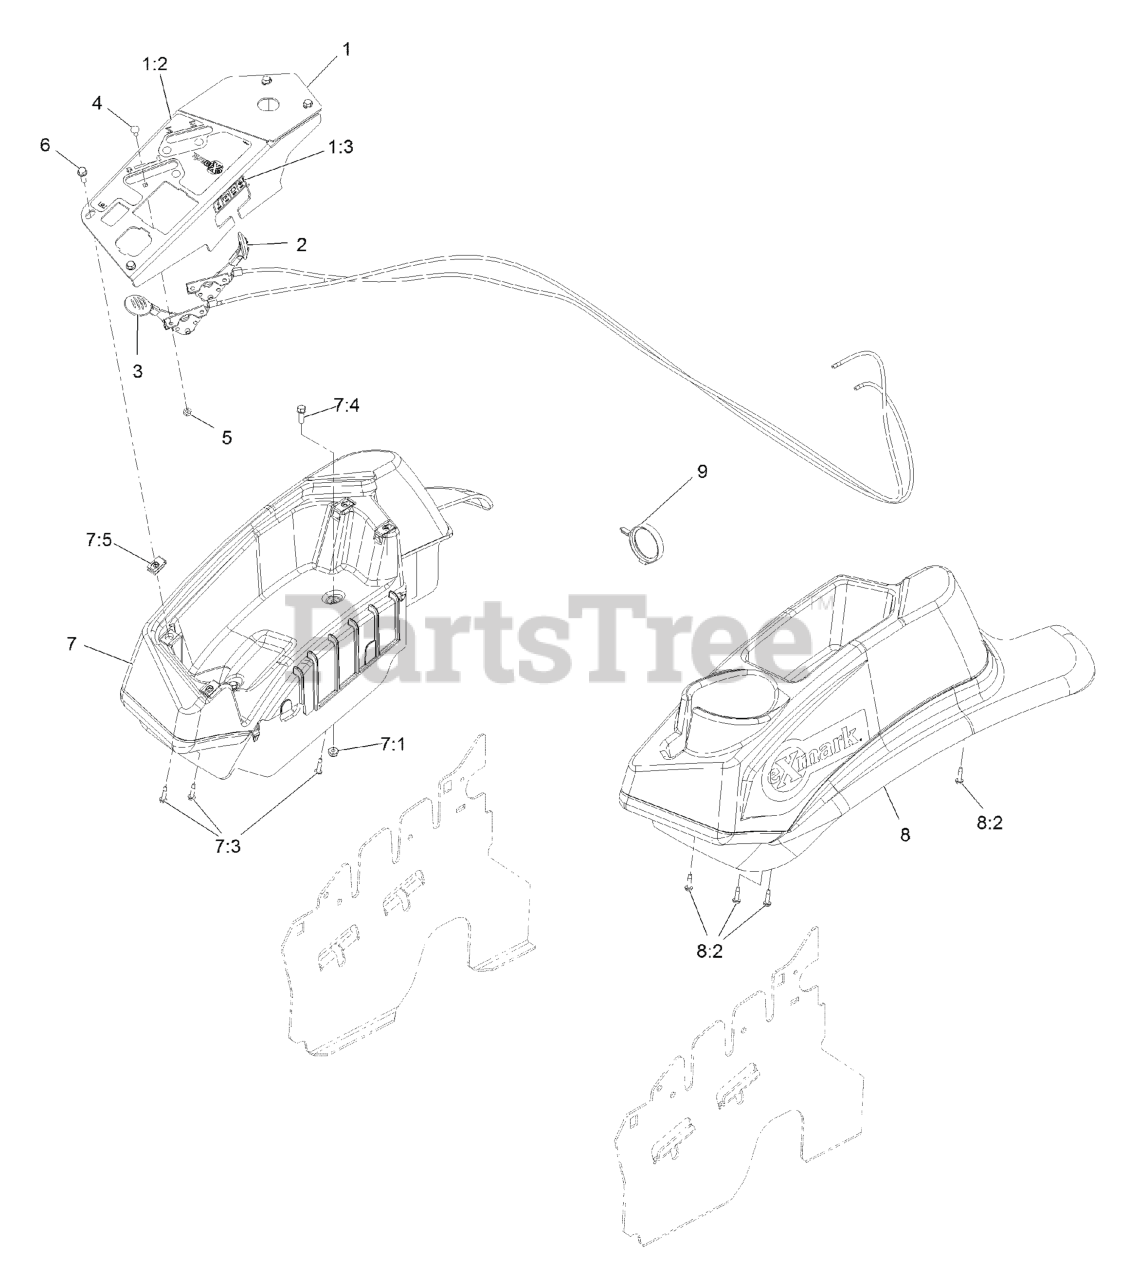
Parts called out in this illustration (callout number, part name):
1	CONSOLE,PANEL W/DECAL
1:2	DECAL-CONTROL PANEL NON-E
1:3	DECAL-FUSES
2	ASM, CHOKE CABLE
3	ASM,THROTTLE CABLE
4	BOLT-CARR
5	NUT-LOCK, NI
6	SCREW-HWH
7	CONSOLE,RH NARROW ASM
7:3	SCREW,THD FORM,HWH
7:4	SCREW-HWH
8	CONSOLE.LH NARROW ASM
8:2	SCREW,THD FORM,HWH
9	CLAMP-HARNESS
